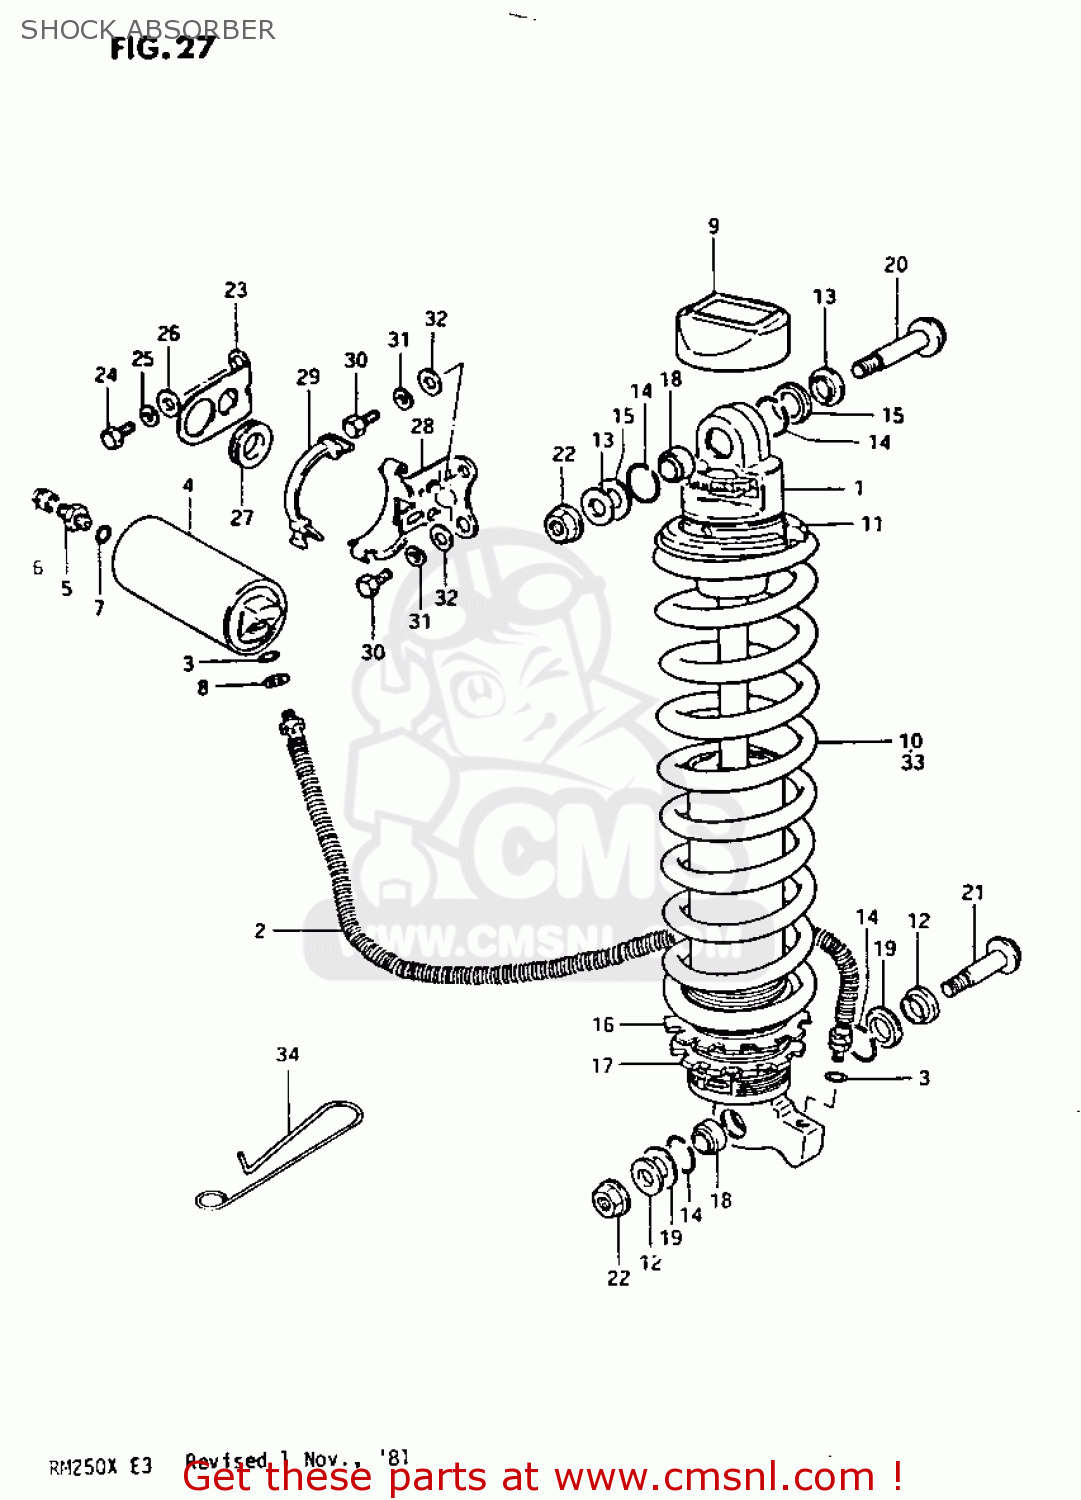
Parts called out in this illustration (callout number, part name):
1	ABSORBER ASSEMBLY,REAR SHOCK
2	HOSE,REAR SHOCK ABSORBER
3	O-RING,RESERVE TANK
4	RESERVE TANK,REAR SHOCK
5	VALVE ASSEMBLY,REAR CUSHION
6	CAP,VALVE AIR
7	O RING
8	WASHER,REAR SHOCK HOSE
9	CAP REAR SHOCK
10	SPRING
11	SPRING, GUIDE
12	COLLAR
13	SPACER,REAR SHOCK,UPPER
14	RING,STOPPER
15	DUST SEAL,UPR
16	GUIDE,SPRING
17	GUIDE,REAR SHOCK ABSORBER SPRING
18	BEARING
19	DUST SEAL,LWR
20	BOLT
21	BOLT(10X54)
22	NUT
23	BRACKET,RESERVOIR TANK
24	BOLT
25	WASHER,LOCK
26	WASHER
27	CUSHION,RESERVOIR TANK
28	BRACKET,RESERVOIR TANK
29	BAND
30	BOLT
31	WASHER,LOCK
32	WASHER
33	SPRING
34	GUIDE RES HOSE CLAMP
